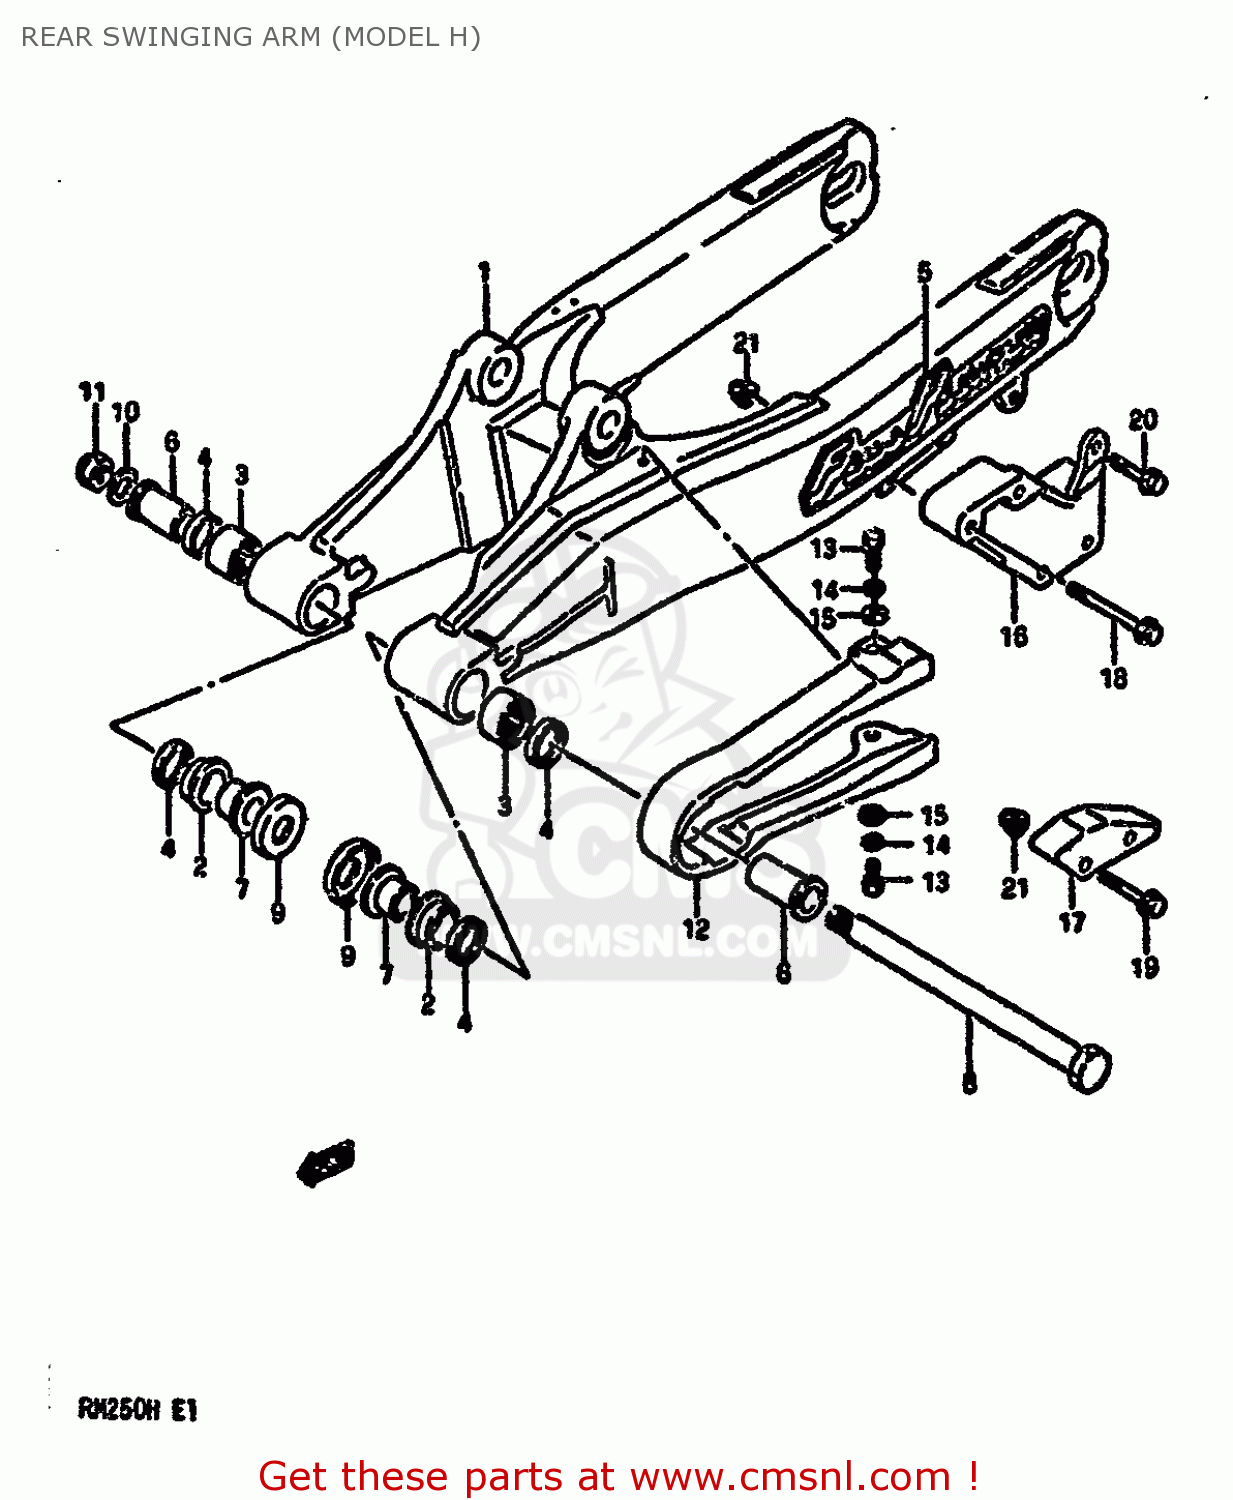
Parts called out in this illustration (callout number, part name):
1	SWING ARM ASSEMBLY,REAR
2	BUSHING,REAR SWING ARM PIVOT
3	BEARING(20X27X30)
4	OIL SEAL
5	LABEL (FRONT CARRIER WARNING)
6	SPACER,RR SWINGING ARM PIVOT
7	SPACER,RR SWGARM PIVOT INNER
8	SHAFT,RR SWINGINGARM PIVOT
9	COVER,RR SWGARM DUST SEAL
10	WASHER(14.5X29X2.3)
11	NUT
12	BUFFER,CHAIN TOUCH DEFLECTOR
13	BOLT
14	WASHER,LOCK
15	WASHER(6.5X16X1.2)
16	GUIDE,CHAIN
17	DEFENSE,CHAIN GUIDE
18	BOLT
19	BOLT,UNDER
20	BOLT,REAR
21	NUT
